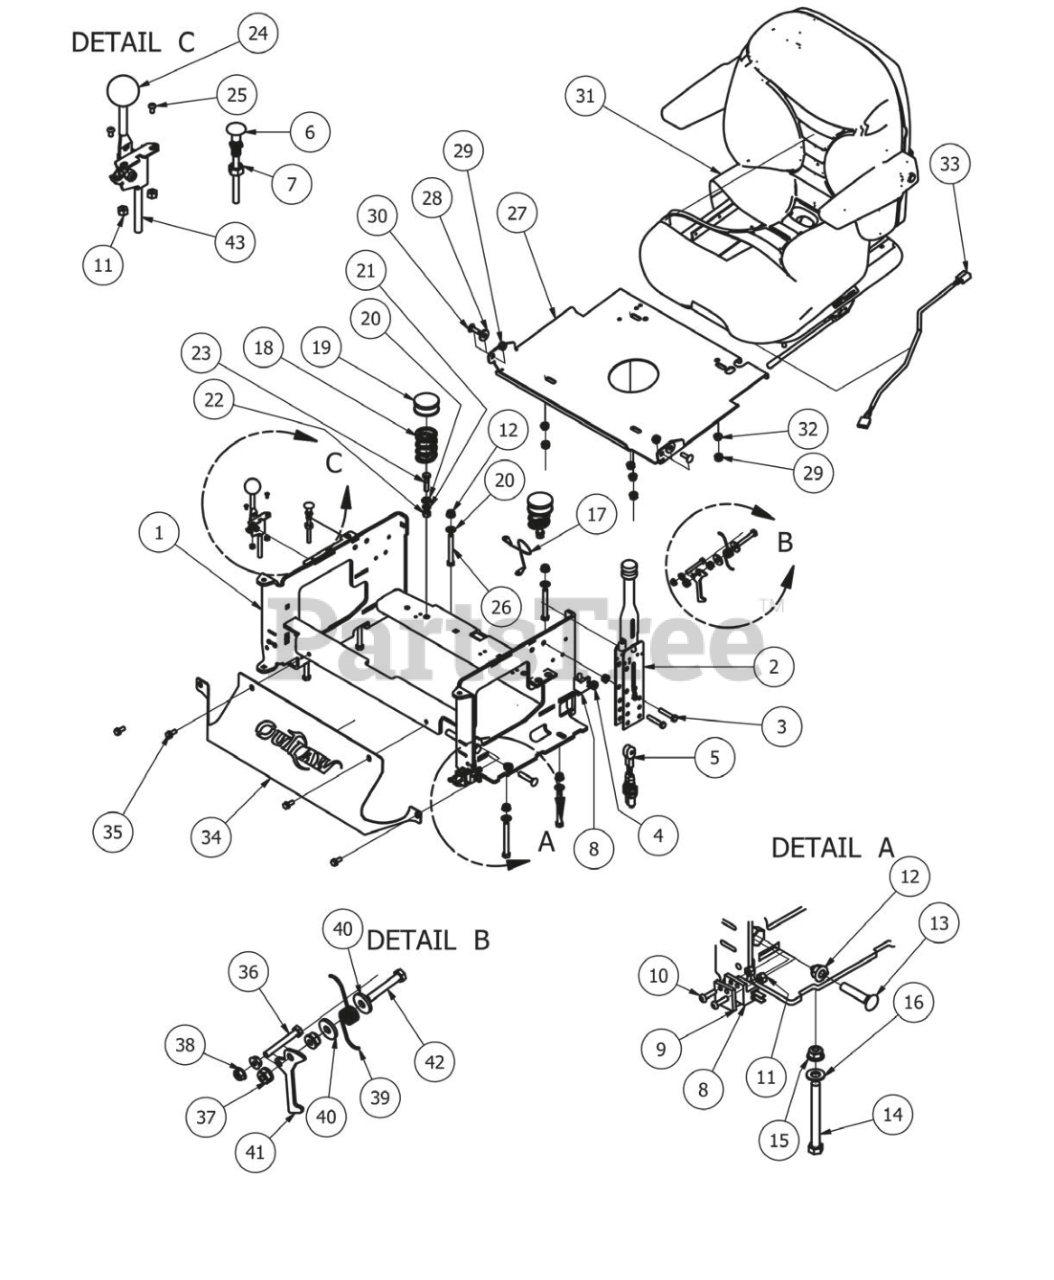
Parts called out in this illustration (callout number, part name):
1	Outlaw Seat Bracket 2012
2	Brake Handle Kit
3	5/16" x 1 3/4" Hex Bolt
4	5/16-18 Nylon Flange Nut
5	Long Brake Cable
7	3/8" Fine Threaded Jam Nut
8	Safety Switch
9	Switch Block Plastic
10	10-24 x 1 BS C/S 18-8 SS
11	10-24 Nylon Insert Locknut
12	3/8" Nylock Flange Nut
13	3/8 × 1 3/4 Carriage Bolt
14	3/8-16x3-1/2 grade 5 hex bolt
15	3/8" Nylock Flange Nut
16	3/8" Flat Washer
17	Seat Cable
18	Seat Spring
19	Spring Cap Cover
20	3/8" Flat Washer
21	3/8" Lock Washer
22	3/8" Hex Nut
23	3/8" x 1 1/2" Hex Bolt
24	Universal Throttle Head - 2012
25	10-24 X 5/8 BS C/S 18-8 SS
26	3/8-16x3 grade 5 hex bolt
27	Seat Plate
28	.360 ID Plastic Washer
29	5/16-18 Nylon Flange Nut
30	5/16" x 1" Carriage Bolt
31	2010 Outlaw Seat
32	5/16" Flange Nut
33	Seat Switch Adapter
34	Outlaw Cooler Cover
35	5/16 x 3/4 washer head type F screw
36	1/4-20 x 2 Hex Bolt
37	5/16-18 Nylon Flange Nut
38	1/4-20 Hex Flange Nuts Zinc w/Serrations
39	Torsion Spring for Seat latch
40	.360 ID Plastic Washer
41	Seat Latch Lever
42	5/16-18 X 2 Hex C/S (GR.5) ZC
43	Outlaw Throttle Cable Only
